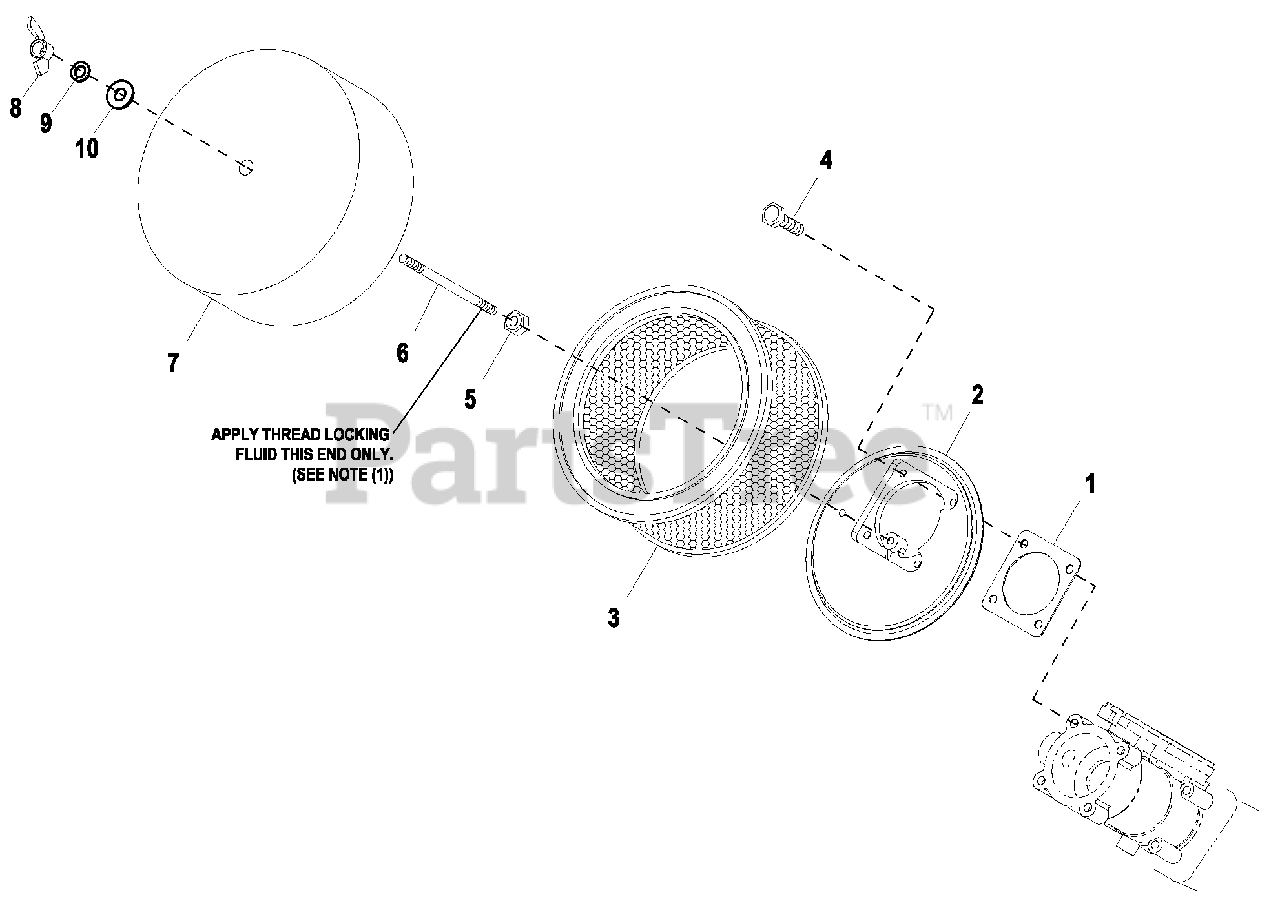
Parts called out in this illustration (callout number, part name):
1	GASKET BOSCH 32 & 40
2	ADAPTER CARBURETOR W/PVC CONN
3	ELE M ENT AIR CLEANER
4	SCREW HHC M5-0.8X16G8.8
5	NUT HEX 1/4-20 STEEL
6	STUD TH 1/4-20 X 4-1/2 G2 ZNC
7	PLATE, AIR CLEANER TOP 2.4L
8	NUT WING 1/4-20
9	WASHER LOCK M6-1/4
10	WASHER FLAT 1/4-M6 ZINC
